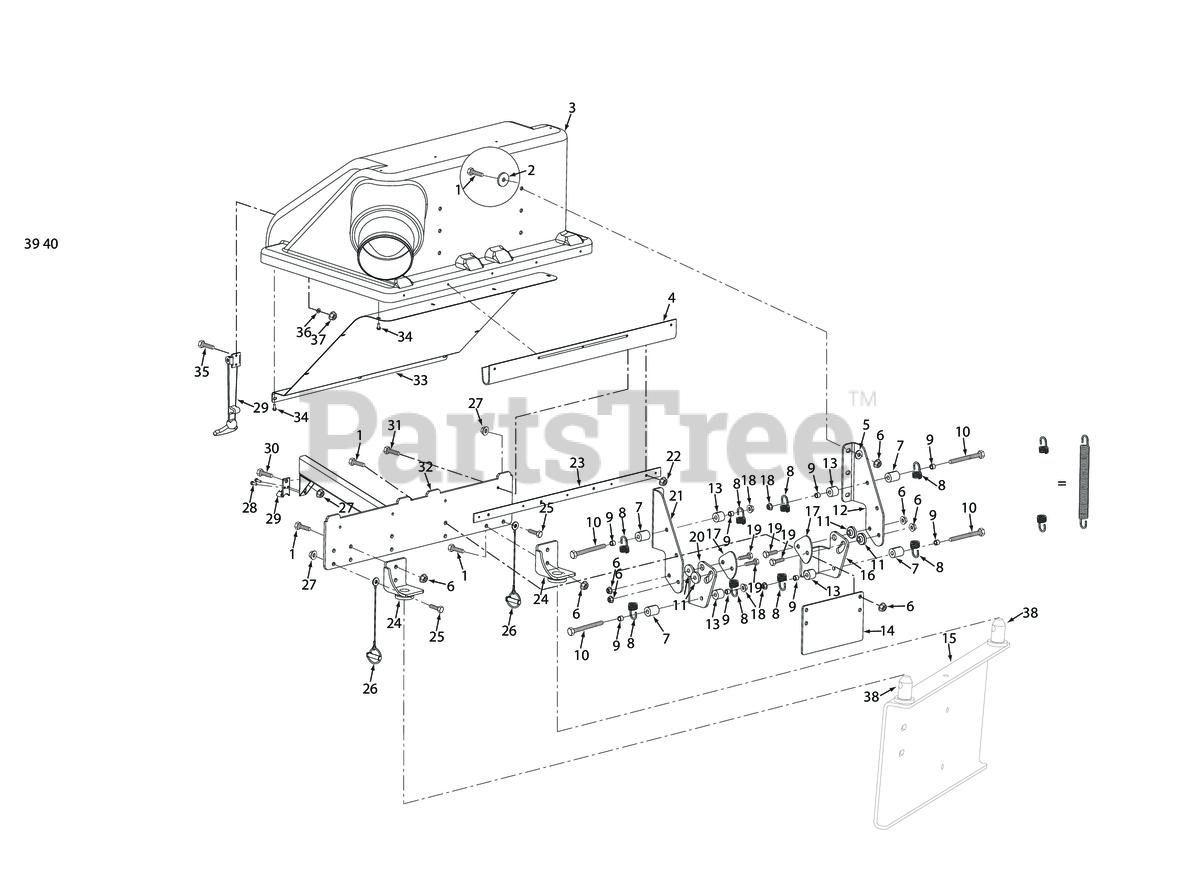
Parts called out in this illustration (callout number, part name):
1	Bolt, Hex Head 3/8-16 x 1-1/4", Kawasaki FX / FS
2	Flatwasher, 3/8-.406 x 1-1-1/2 x 7 Gauge
3	Hood Assembly
4	Diode (part of wire harness)
5	Flatwasher, 3/8" Special (.391 x .938 x .105)
6	HEX NUT, ELASTIC STOP LOCK, 3/8-16
7	Spacer
8	Spring, Hood Hinge
9	Spacer, Deck Assist
10	Bolt, Hex Head 3/8-16 x 4.00
11	Bushing, Hopper Pivot
12	Hinge, Upper LH
13	SPACER, J-PULL ROD
14	Plate, Support
15	Bag Support Plate
16	Hinge, Lower LH
17	Guard, GC Hinge
18	Bolt, Hex Head 3/8-16 x 1" Ser. Flg.
19	Bolt, Hex Head, 3/8-16 x 1-1/2"
20	Hinge, Lower RH
21	Hinge, Upper RH
22	Bolt, Hex Hd. 1/2-13 x 9-1/2"
23	Retainer, Seal
24	Receiver, Weldment
25	Bolt, Heax Head 5/16-18 x 1" (48V / 52V)
26	Quick Pin Assembly
27	HEX NUT, ELASTIC STOP LOCK, 5/16-18
28	Rivot, 3/16 x .402 POP
29	Latch, Hopper
30	BOLT, SERRATED FLANGE HEX HEAD 5/16-18 X 3/4"
31	BOLT, HEX HEAD, 1/4-20 X 3/4 GR.5
32	Frame Weldment, Bag Support
33	Screen, GC Hood
34	Pop Rivet, 3/16 x .652"
35	Screw, #10-32 x 3/4"
36	Flatwasher, 3/16 (.196 x .469 x .048)
37	HEX NUT, ELASTIC STOP LOCK # 10-32
38	Pin, GC Locator
39	Lockwasher, 3/8" Spring, Kawasaki FX / FS
